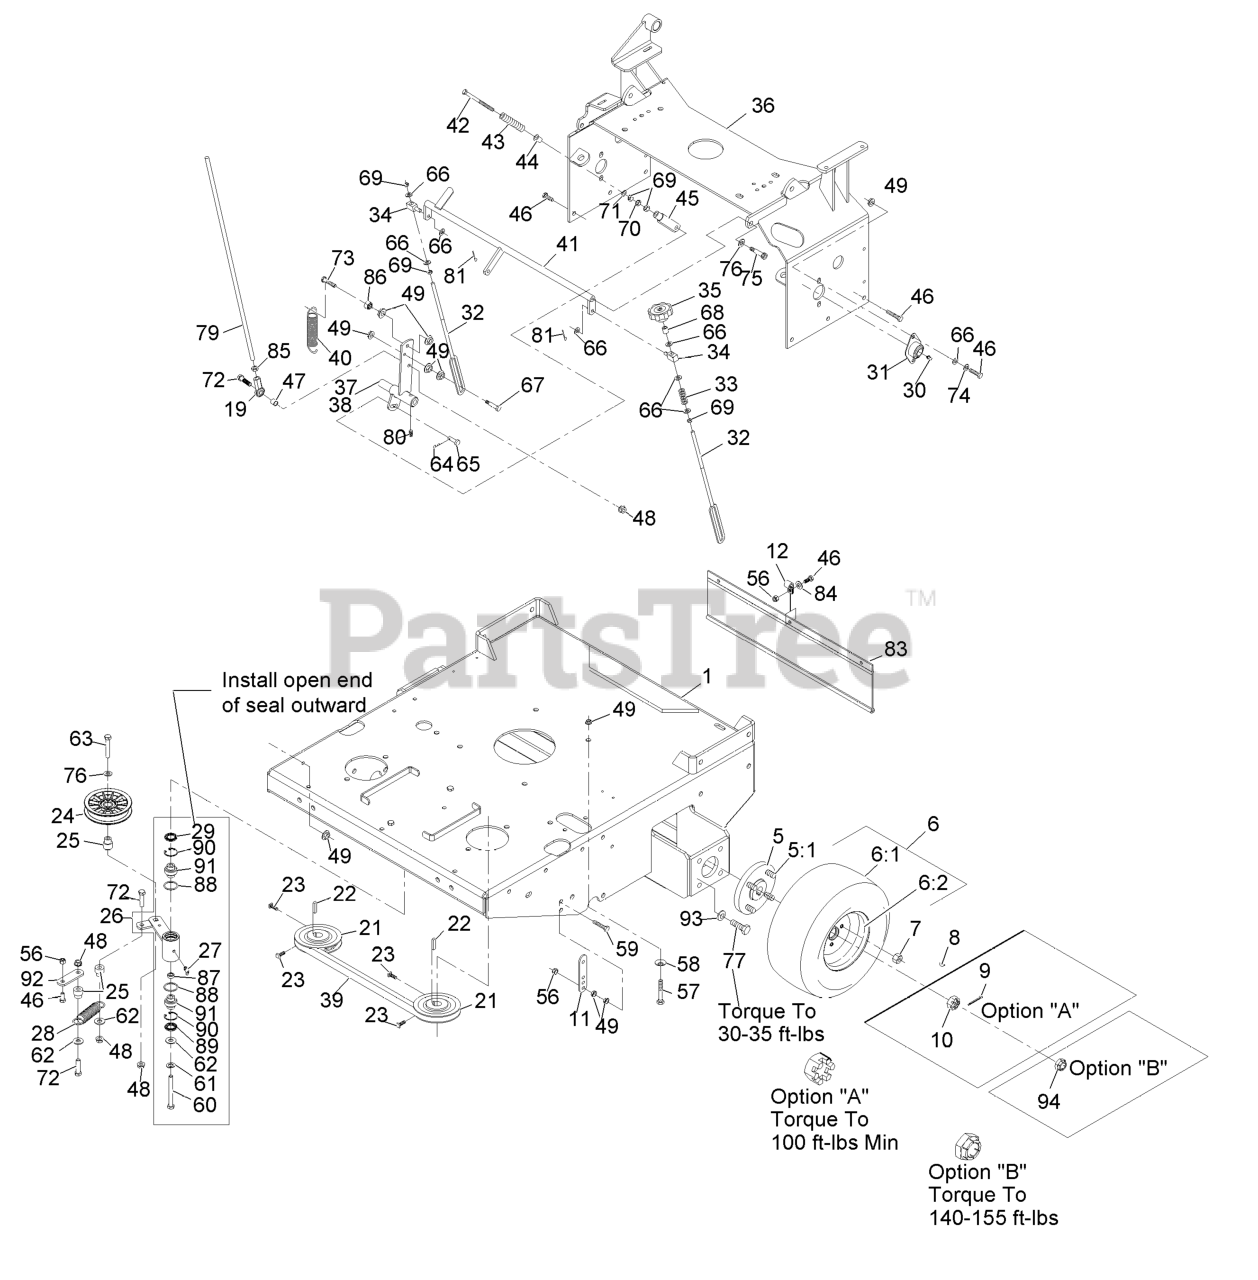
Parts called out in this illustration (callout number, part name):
5:1	STUD-WHEEL
6	ASM, DRIVE TIRE
7	NUT-LUG
8	KEY-WOODRUFF
9	PIN-COTTER
10	NUT-HEX, SLOTTED
11	TAB-SPRING, EXTENSION
12	CLIP-LOOM
19	JOINT-BALL END, LH
21	SHEAVE ASM
23	SCREW-SET
24	PULLEY-IDLER, FLAT
25	BUSHING-IDLER
26	KIT,IDLER ARM W/BRGS.
27	FITTING-GREASE, 90 DEG
28	SPRING-EXTENSION
29	SEAL-LIP, SINGLE
30	FITTING-GREASE
31	BEARING-FLANGE, SIDE
32	LINK,SPEED CONTROL
33	SPRING-COMPRESSION
35	KNOB-TRACKING
36	WLD,FUEL TANK SUPPORT TT
37	WLD,LH CONTROL ARM
39	BELT,COG A-59.5
40	SPRING-EXTENSION
41	WLD,CRANK SPEED CNTRL
42	BOLT-RETURN, NEUTRAL
43	SPRING,COMPRESSION (NEUT)
44	BUSHING-FLANGED
45	YOKE-ADJUSTABLE
46	SCREW-HH
47	TUBE,PUMP LINK SPACER
48	NUT-HHF, WHIZ
56	NUT-LOCK, NI
57	SCREW-HH
58	WASHER-BELLEVILLE
59	BOLT-TAP, HH
60	SCREW-HH
61	WASHER-LOCK
62	WASHER-FLAT
63	SCREW-HH
64	PIN-COTTER
65	PIN-CLEVIS
66	WASHER-PLAIN
67	SCREW-HH
69	NUT-HEX
70	NUT-JAM
71	WASHER-FLAT
72	SCREW-HH
73	SCREW-HH, SPECIAL
74	WASHER-LOCK
75	SCREW-HSH
76	WASHER-FLAT
77	SCREW-HH
79	LINK,DRIVE (PLTD)
80	SCREW-SET
81	PIN-COTTER
83	SHIELD,DRAG
84	WASHER-FLAT
85	NUT-HEX JAM, LH
86	NUT-JAM
89	SEAL-LIP, DOUBLE
90	RING-SNAP
91	BEARING-SPHERICAL
92	ARM-LIFT, DECK
93	WASHER-BELLEVILLE
94	NUT-LOCK
